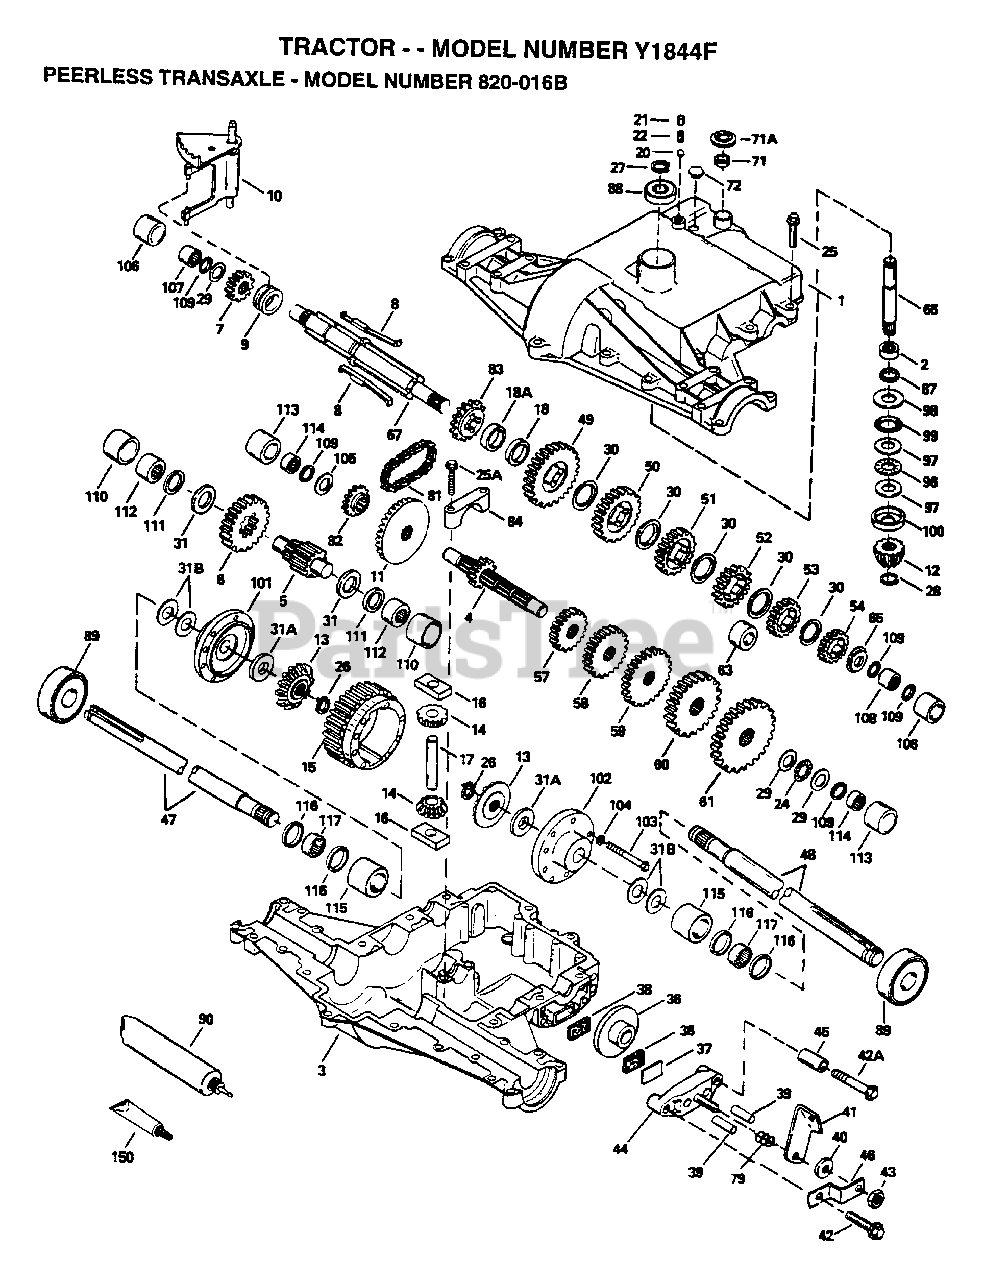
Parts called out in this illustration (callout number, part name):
1	COVER TRANSAXLE
2	BEARING NEEDLE
3	CASE TRANSAXLE
4	SHAFT COUNTER
5	SHAFT, OUTPUT, 9T
6	GEAR, OUTPUT, 35T
7	GEAR, SPUR, 15T
9	COLLAR SHIFT
10	COLLAR SHIFT
11	GEAR BEVEL, 33T
12	BEVEL PINION, 13T
14	PINION, 10T
15	GEAR, RING, 31T
16	BLOCK DRIVE
18	SPACER, .350/.340 THICK
18A	SPACER, .276/.268 THICK
20	BALL STEEL, 5/16" DIA.
21	SCREW, 3/8-16 X 3/8"
24	THRUST BEARING
25	SCREW HEX HD 5/16-18 X 1-1/4
25A	SCREW, 1/4-20 X 1-1/4
28	RETAINING RING
29	WASHER THRUST
30	WASHER THRUST
31	WASHER THRUST
31B	WASHER THRUST
37	PLATE BRAKE PAD
41	LEVER BRAKE
42	SCREW, 1/4-20 X 1-1/4
42A	SCREW, 1/4-20 X 2-1/4
43	LOCKNUT 5/16-24
44	HOLDER BRAKE PAD
46	BRKT BRAKE LEVER
47	AXLE, 12-5/16" LONG
48	AXLE, 16-3/16" LONG
49	GEAR, SPUR, 41T
50	GEAR, SPUR, 35T
51	GEAR, SPUR, 30T
52	GEAR, SPUR, 25T
53	GEAR, SPUR, 22T
54	GEAR, SPUR, 19T
57	GEAR, SPUR, 15T
58	GEAR, SPUR, 20T
59	GEAR, SPUR, 25T
60	GEAR, SPUR, 28T
61	GEAR, SPUR, 31T
66	SHAFT INPUT
67	SHAFT BRAKE
71	SEAL SQUARE CUT
72	PLUG, THRDED, 9/16-18
81	CHAIN, ROLLER
82	SPROCKET 9T
83	SPROCKET 18T (REV)
84	BEARING CAP
87	OIL SEAL 3/4
88	BEARING BALL
89	BEARING BALL
90	GREASE BENTONITE, 32 OZ.
96	BEARING THRUST
97	WASHER THRUST
100	WASHER CUPPED
101	CARRIER DIFF THREADED HOLES
102	CARRIER DIFF
103	SCREW, 1/4-20 X 2-1/4
104	WASHER LOCK 1/4
107	BEARING NEEDLE
108	BEARING NEEDLE
110	SLEEVE STEPPED
111	RING SQ CUT
112	BEARING NEEDLE CAPPED
113	SLEEVE STEPPED
114	BEARING NEEDLE CAPPED
115	SLEEVE STEPPED
116	RING SQ CUT
117	BEARING NEEDLE
150	GASKET ELIMINATOR
